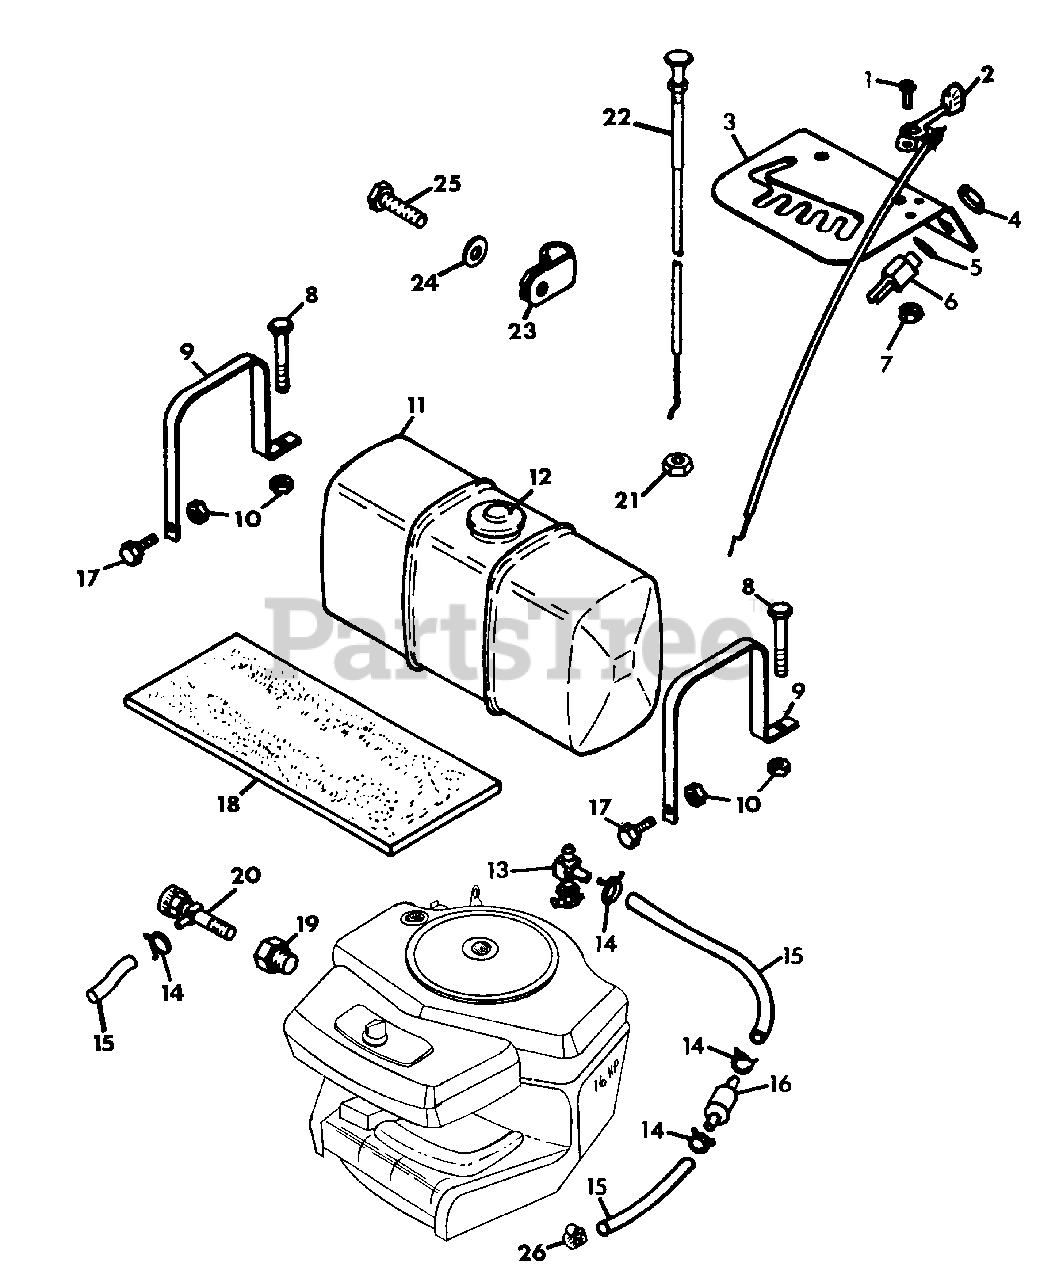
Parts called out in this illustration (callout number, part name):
1	CASE, TRANSMISSION
2	COVER, TRANSMISSION
3	SHAFT, OUTPUT
4	GEAR, SPUR (20 TEETH)
5	GEAR, SPUR (22 TEETH)
6	GEAR, SPUR (25 TEETH)
7	GEAR, SPUR (30 TEETH)
8	GEAR, SPUR (35 TEETH)
9	COLLAR, SHIFT
10	SPROCKET (18 TEETH)
11	SPROCKET (9 TEETH)
12	SHAFT, COUNTER
13	GEAR, BEVEL (42 TEETH AND 15 TOOTH SPUR GEAR)
14	GEAR, SPUR (20 TEETH)
15	GEAR, SPUR (25 TEETH)
16	GEAR, SPUR (28 TEETH)
17	GEAR, SPUR (30 TEETH)
18	SHAFT, INPUT
19	BEVEL PINION, INPUT
20	SPROCKET (8 TEETH)
27	BUSHING, FLANGED
28	CHAIN, ROLLER (NO. 41 CHAIN, 24 LINKS)
29	RACE, THRUST
30	BEARING, NEEDLE
31	RING, RETAINING
32	RING, RETAINING
34	RING, RETAINING
35	ROD & FORK ASSY., SHIFT
36	SCREW, HEX HD. TAP-TITE, 1/4-20X1-1/4
41	SCREW, SET 3/8-16X3/8
43	WASHER, THRUST
